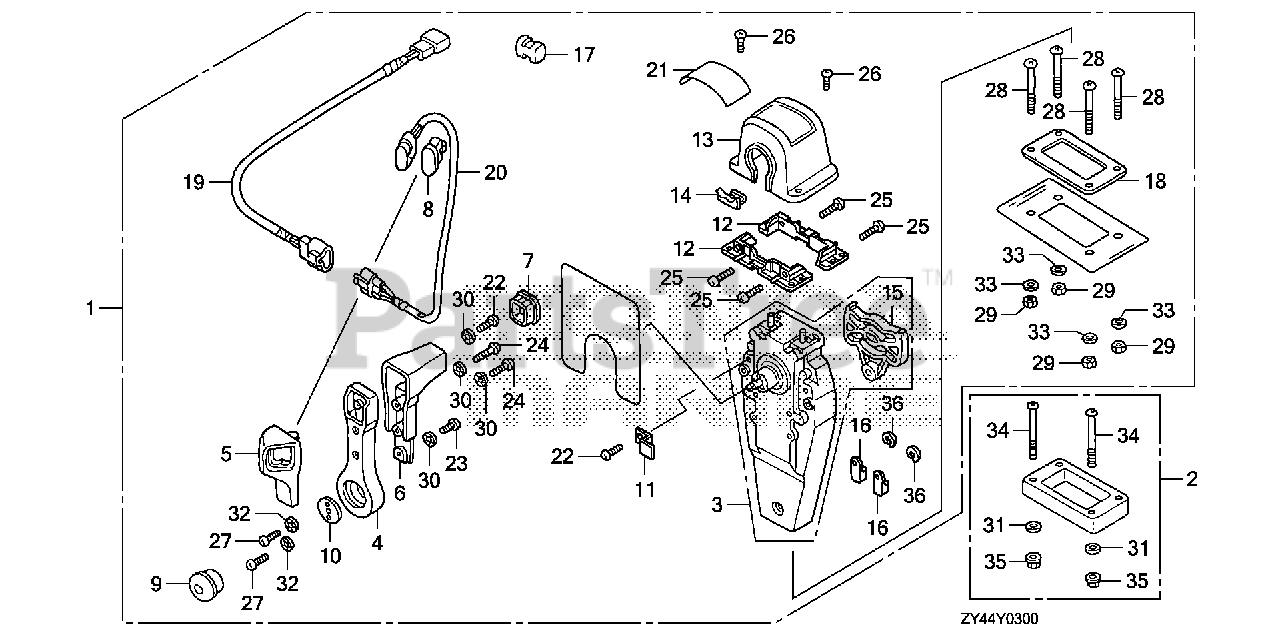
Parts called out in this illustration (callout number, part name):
1	BOX KIT, REMOTE CONTROL (TOP MOUNT SINGLE)(R)
2	SPACER KIT, REMOTE CONTROL BOX (TOP MOUNT SINGLE)
3	HOUSING ASSY., L. (INNER) (TOP MOUNT)
4	HANDLE, REMOTE CONTROL
5	COVER, L. GRIP
6	GRIP, REMOTE CONTROL HANDLE
7	CAP, GRIP
8	CAP, SWITCH
9	BUTTON, THROTTLE
10	PLATE, HANDLE
11	PLATE, CABLE CLAMP
12	BRACKET, REMOTE CONTROL HOUSING
13	HOUSING, REMOTE CONTROL BOX
14	HOUSING, LEAD
15	PLATE, DWELL
16	TERMINAL, CABLE
17	SPACER, CABLE CLAMP
18	GASKET, SINGLE
19	SUB-HARNESS ASSY., POWER TRIM-TILT (A)
20	SWITCH ASSY., POWER TRIM-TILT (A)
21	MARK, REMOTE CONTROL (SINGLE)
22	SCREW, PAN (5X16)
23	SCREW, PAN (5X10)
24	SCREW, PAN (5X20)
25	SCREW, PAN (5X18)
26	SCREW, PAN (4X10)
27	SCREW, PAN (6X18)
28	SCREW, PAN (5X40)
29	NUT, HEX. (5MM)
30	WASHER, LOCK (5MM)
31	WASHER, PLAIN (5MM)
32	WASHER, LOCK (6MM)
33	WASHER, PLAIN (5MM)
34	SCREW, PAN (5X65)
35	NUT, HEX. (5MM)
36	E-RING (6MM)
